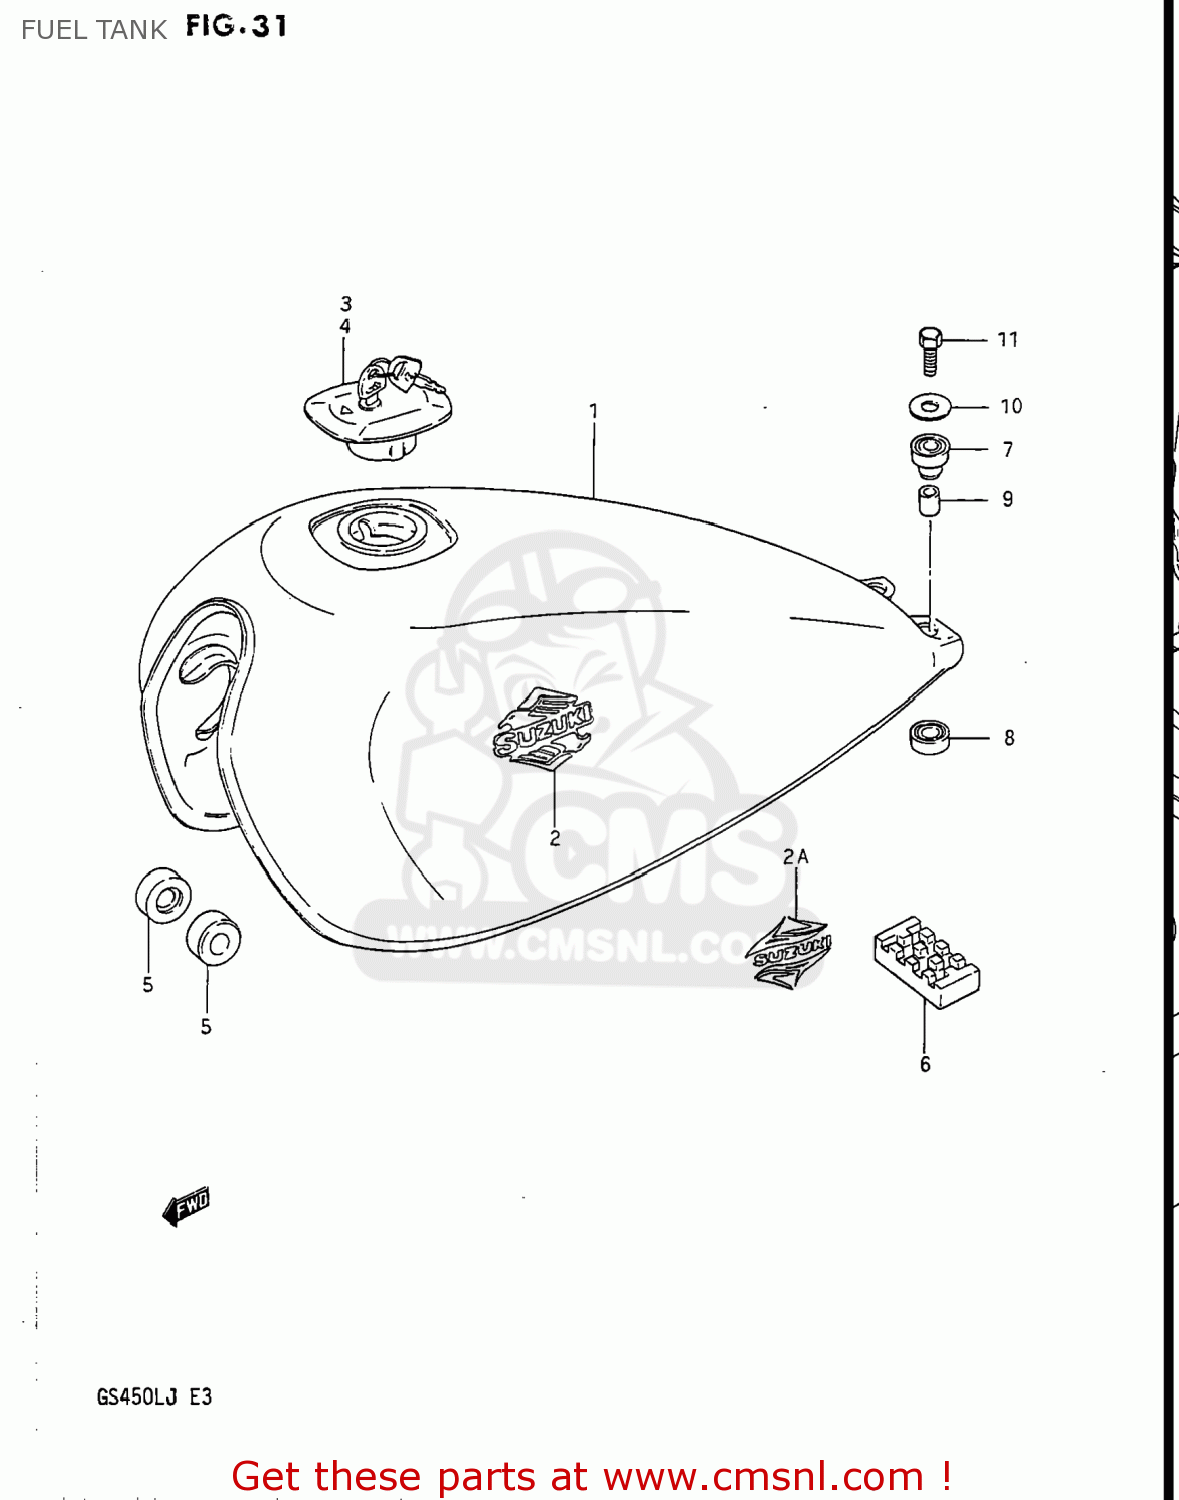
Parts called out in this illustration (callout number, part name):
1	TANK ASSEMBLY,FUEL
2	EMBLEM,FUEL TANK
2A	EMBLEM,FUEL TANK
3	CAP SET,FUEL TANK
4	CAP SET,FUEL TANK
5	CUSHION
6	CUSHION
7	CUSHION
8	CUSHION
9	SPACER (6.4X9X20)
10	WASHER (6.5X24X1.6)
11	BOLT
